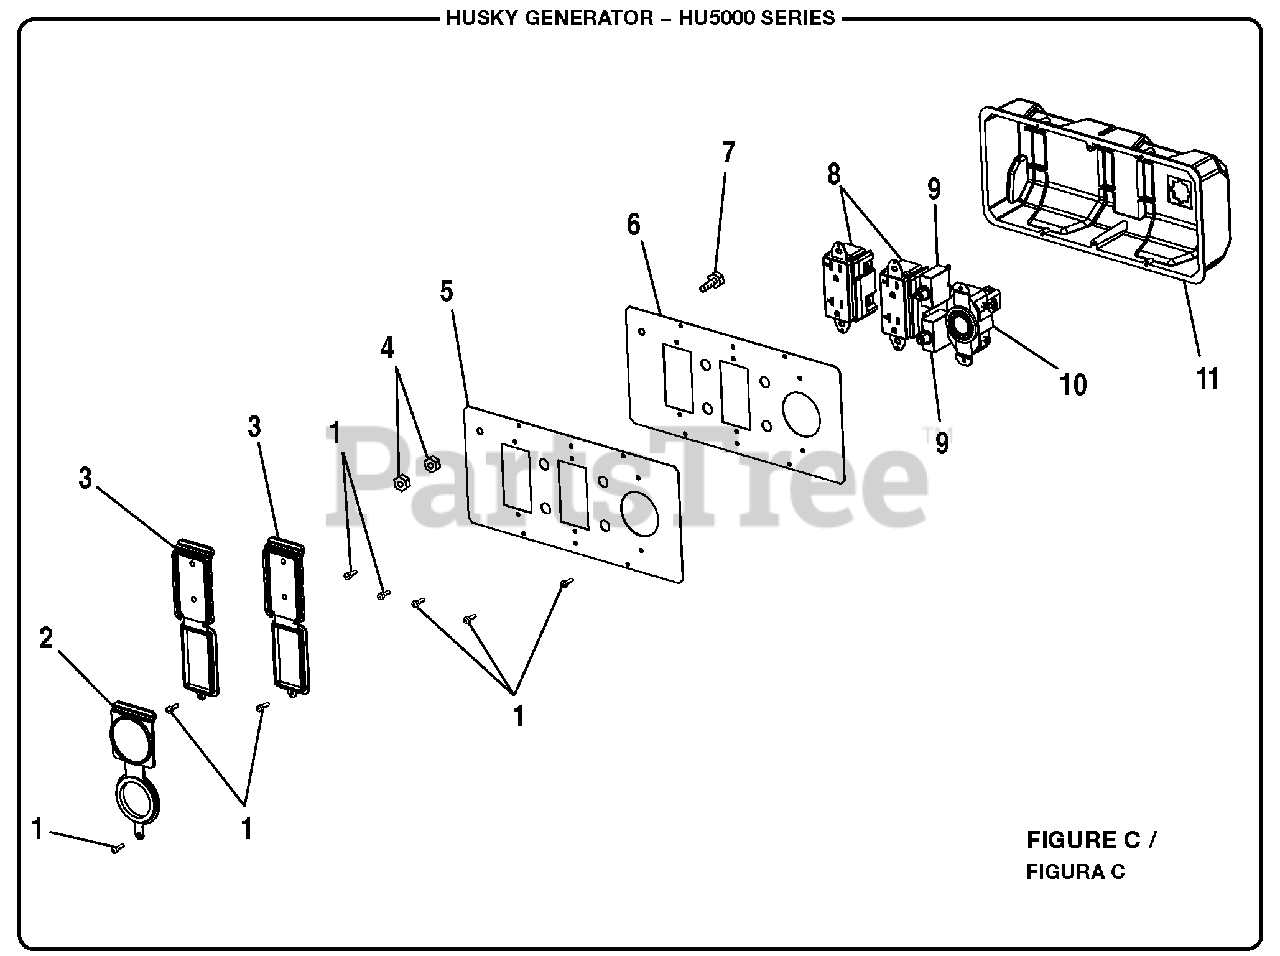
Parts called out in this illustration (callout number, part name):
1	Screw (6-20 x 3/8 in.)
2	Outlet Cover (240 Volt)
3	Outlet Cover (120 Volt)
4	Hex nut (1/4-20)
5	Electrical Outlet Label
6	Cover Plate
7	Screw (1/4-20 x 5/8 in., Hex Hd)
8	Duplex Receptacle (120/240 Volt, 20 Amp)
9	Circuit Breaker (20 Amp, 125 Volt)
10	Twist lock Receptacle (120/240 Volt, 20 Amp)
11	Rear Control Panel
